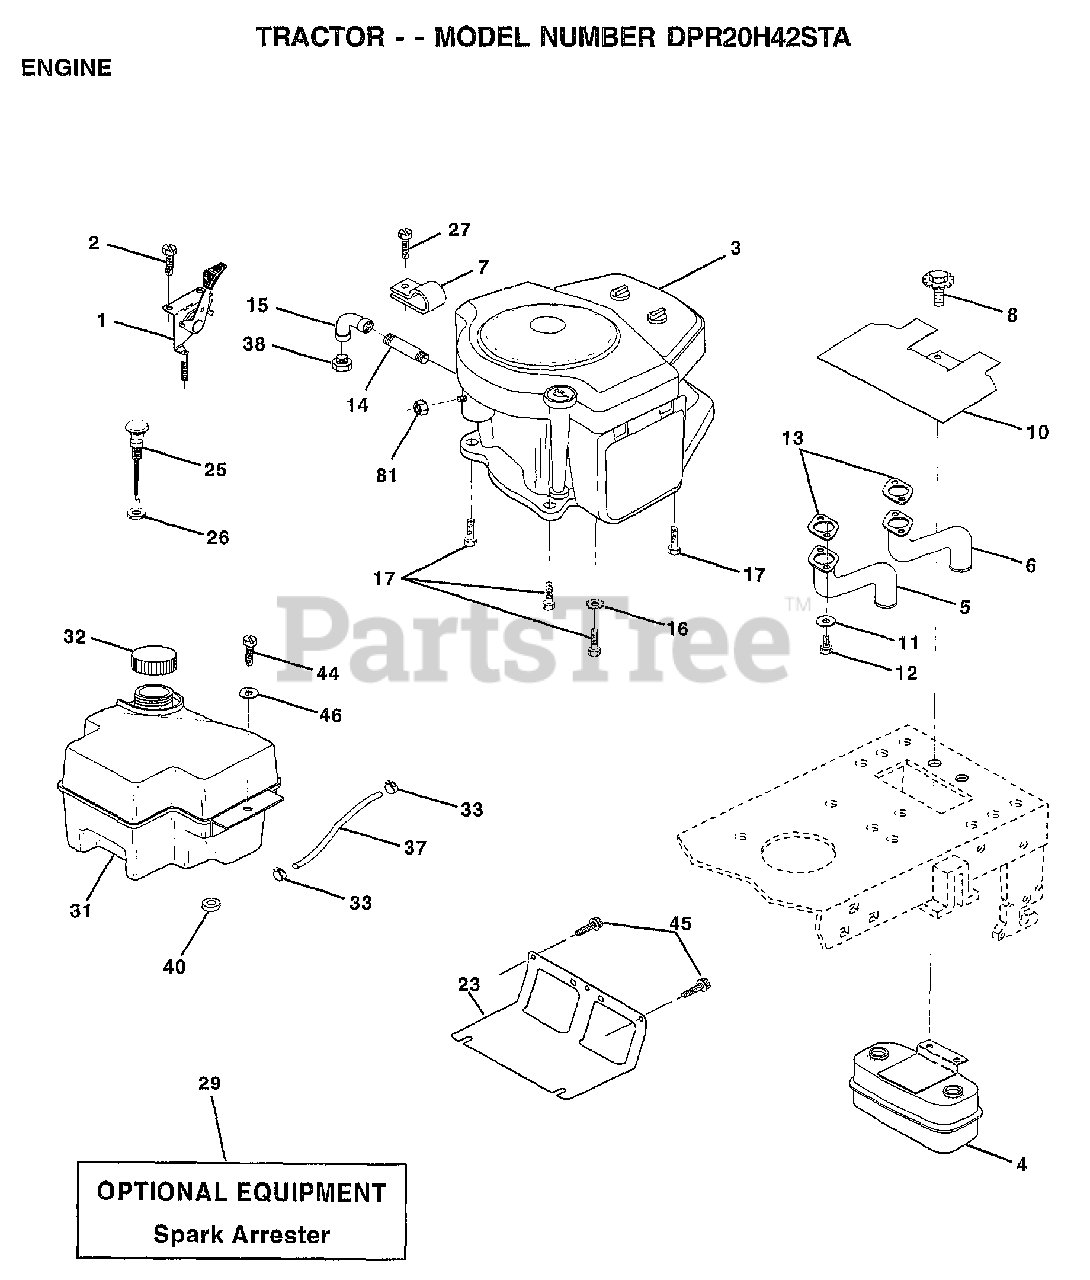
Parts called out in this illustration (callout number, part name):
1	CONTROL THRT 35.5
2	SCREW LT
4	MUFFLER.TW.LOTONE
5	EXHAUST.B&S.18.LH
6	EXHAUST.B&S.18.RH
7	CLAMP.TUBE.DBL.EN
8	BOLT.5/16-18.UNC
10	SHIELD.HEAT.
11	LOCKWASHER
13	GASKET MUFFLER
14	PIPE NIPPLE LT
15	ELBOW
16	LOCKWASHER
17	SCREW LT
23	SHIELD BROWNING
25	CONTROL.CHOKE.37
26	"NUT,KEPS 3/8-24IM"
27	"SCREW-TT,10-32 FL"
31	TANK.FUEL.FRONT.
32	CAP ASM FUEL
33	HOSE CLAMP
37	LINE FUEL
44	SCREW
45	SCREW
46	WASHER
81	NUT
